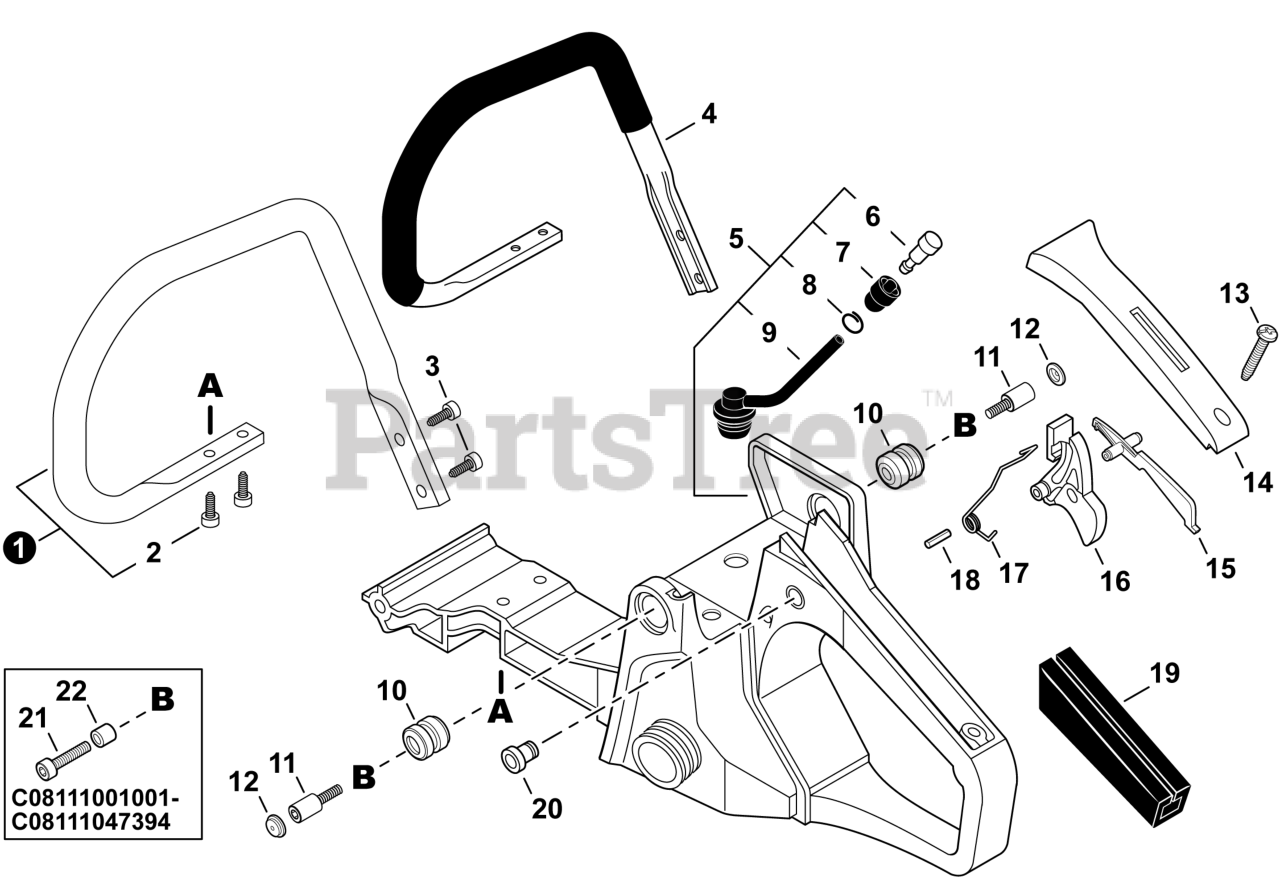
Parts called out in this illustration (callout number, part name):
1	HANDLE SET, FRONT - NYLON
2	SCREW TAPPING 5×20
3	SCREW TAPPING 5×20
4	HANDLE, FRONT - ALUMINUM
5	HANDLE ASSY, REAR
6	VENT ASSY
7	HOLDER, VENT
8	CLIP Ø6.5 MM
9	PIPE, VENT 3×6×65
10	CUSHION 4
11	BOLT 4×10×13.5
12	CAP, CUSHION
13	SCREW 4×14
14	COVER, HANDLE
15	LOCKOUT, THROTTLE
16	TRIGGER, THROTTLE
17	SPRING, TORSION
18	PIN, SPRING 4×30
19	GRIP, HANDLE
21	BOLT, HEX 4×20
22	COLLAR 4.2×7×9.5
